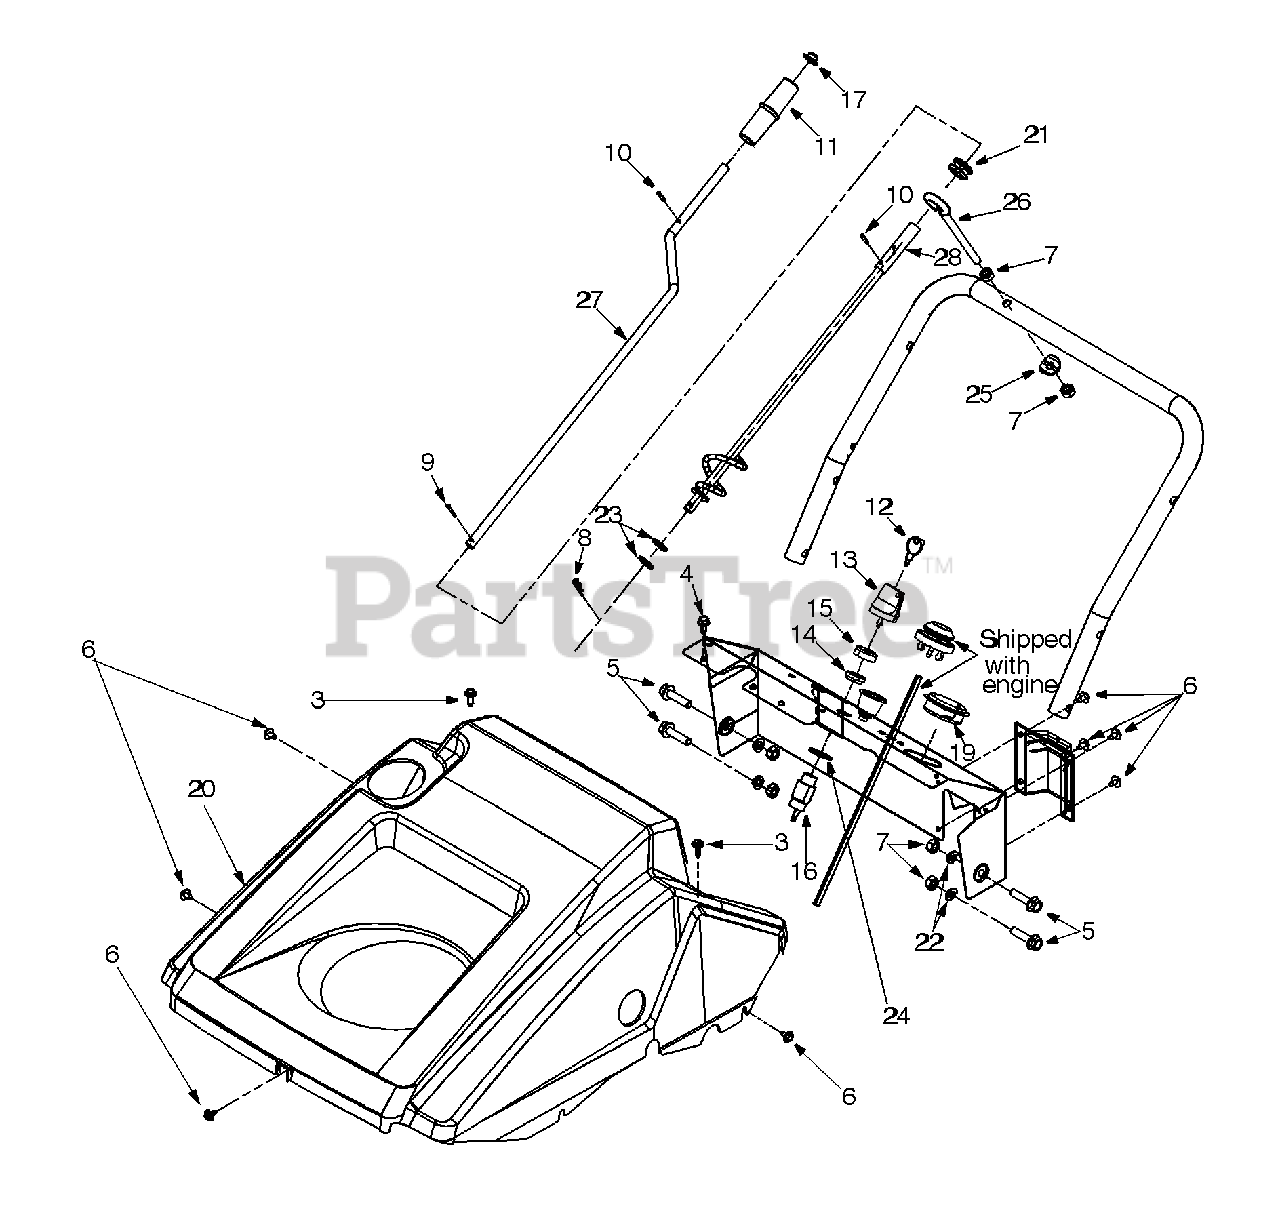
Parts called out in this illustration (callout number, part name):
4	B Screw 1/4-14 x 0.5"
5	Hex Flange Screw
6	Special Screw
7	Hex Nut: 5/16-18
8	Cotter Pin
9	Cotter Pin
10	Roll Pin
11	Chute Crank Knob
12	Ignition Key
13	Ignition Key w/o Logo
14	Ignition Switch Nut
15	Ignition Switch Cap
16	Switch: Key Recoil Start
19	Cap
20	Engine Shroud: Beige
21	Rubber Grommet
22	Lock Washer
23	Flat Washer
24	Internal Lock Washer
25	Saddle Washer
28	Spacer
